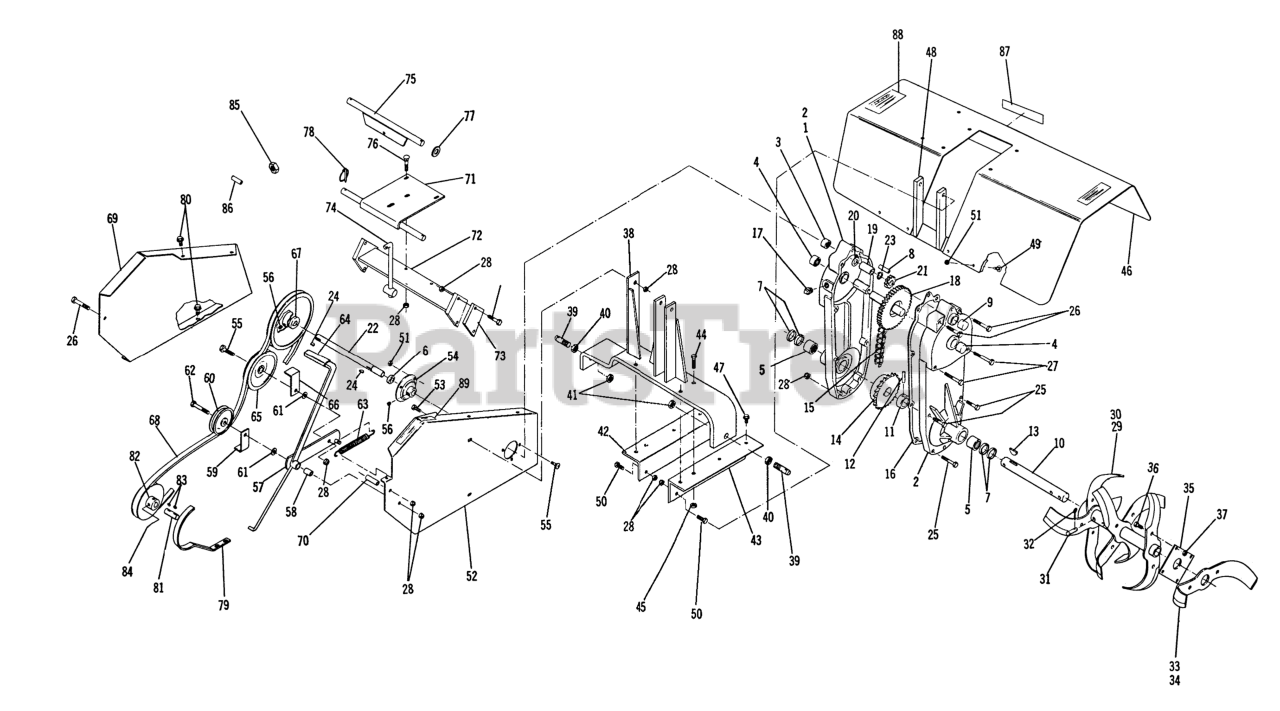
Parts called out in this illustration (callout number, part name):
1	Gear Case-Complete
2	Case
3	BEARING-NEEDLE
4	BEARING-NEEDLE
5	BEARING-NEEDLE
6	Seal
7	Seal 1 1/4 I.D.
8	ROLL PIN 3/8 X 1
9	BEARING-NEEDLE
10	Shaft-Tine
11	Spacer
12	ROLL PIN 5/16 X 2
13	#128 Woodruff Key
14	Sprocket 20T
15	CHAIN
16	Gasket
17	SOLID PIPE PLUG
18	Gear-Reduction
19	Spacer
20	WASHER-THRUST
21	GEAR-PINION
22	Shaft Input
23	RING-SNAP, EXTERNAL
24	Key
25	Bolt 3/8-16 x 2 1/2
26	Bolt 3/8-16 x 3 3/4"
27	Bolt Hex 3/8-16 x 5
28	3/8-16 E.S.
29	Tine R.H.
30	Tine L.H.
31	PIN-CLEVIS
32	Cotter Pin
33	R.H. Tine
34	L.H. Tine
35	Plate-Tine Mounting
36	Bolt, 7/16 14 x 1
37	Nut 7/16-14 Nylok
38	Tiller Mast
39	Pin-Lower Link
40	Hex Jam Nut 5/8-11
41	Nut Hex 5/8-11 Eslok
42	Bar-Tiller Support R.H.
43	Bar-Tiller Support L.H.
44	Bolt Hex 1/2-13 x 1 1/2
45	Nut-ES 1/2-13
46	Tiller Shield
47	Bolt Whizlock 3/8-16 x 5/8
48	Tine Shield Mounting Bracket
49	Bolt-Car. 5/16-18 x 1
50	Bolt 3/8-16 x 1
51	Nut 5/16-18
52	Idler Support Plate
53	Bolt 3/8-16 x 1
54	Bearing-Flanged
55	Bolt Hex 5/16-18 x 3/4
56	Set Screw
57	Idler Arm
58	Bushing-Spacer
59	Bracket Belt Guide
60	Idler Pulley
61	Washer
62	Bolt Hex 3 1/4
63	SPRING R
64	Grip
65	PULLEY-IDLER
66	Bracket-Belt Guard
67	Pulley-Driven
68	"V" Belt-Drive
69	Guard-Belt
70	Spacer-Belt Guard
71	Mounting Bracket
72	Brace
73	Plate
75	Anchor Bracket
76	Bolt-Carriage 1 1/2
77	Washer
78	HITCH PIN ASSY
79	Guide-Belt
80	Bolt, 5/16-18 x 1/2
81	Shaft Tiller Stub
82	PULLEY
83	WOODRUFF KEY
84	Setscrew-Square Head
85	Nut 3/1-10 Jam
86	PIN-ROLL
87	Decal-Wheel
88	Decal-Caution
89	Decal-Clutch
